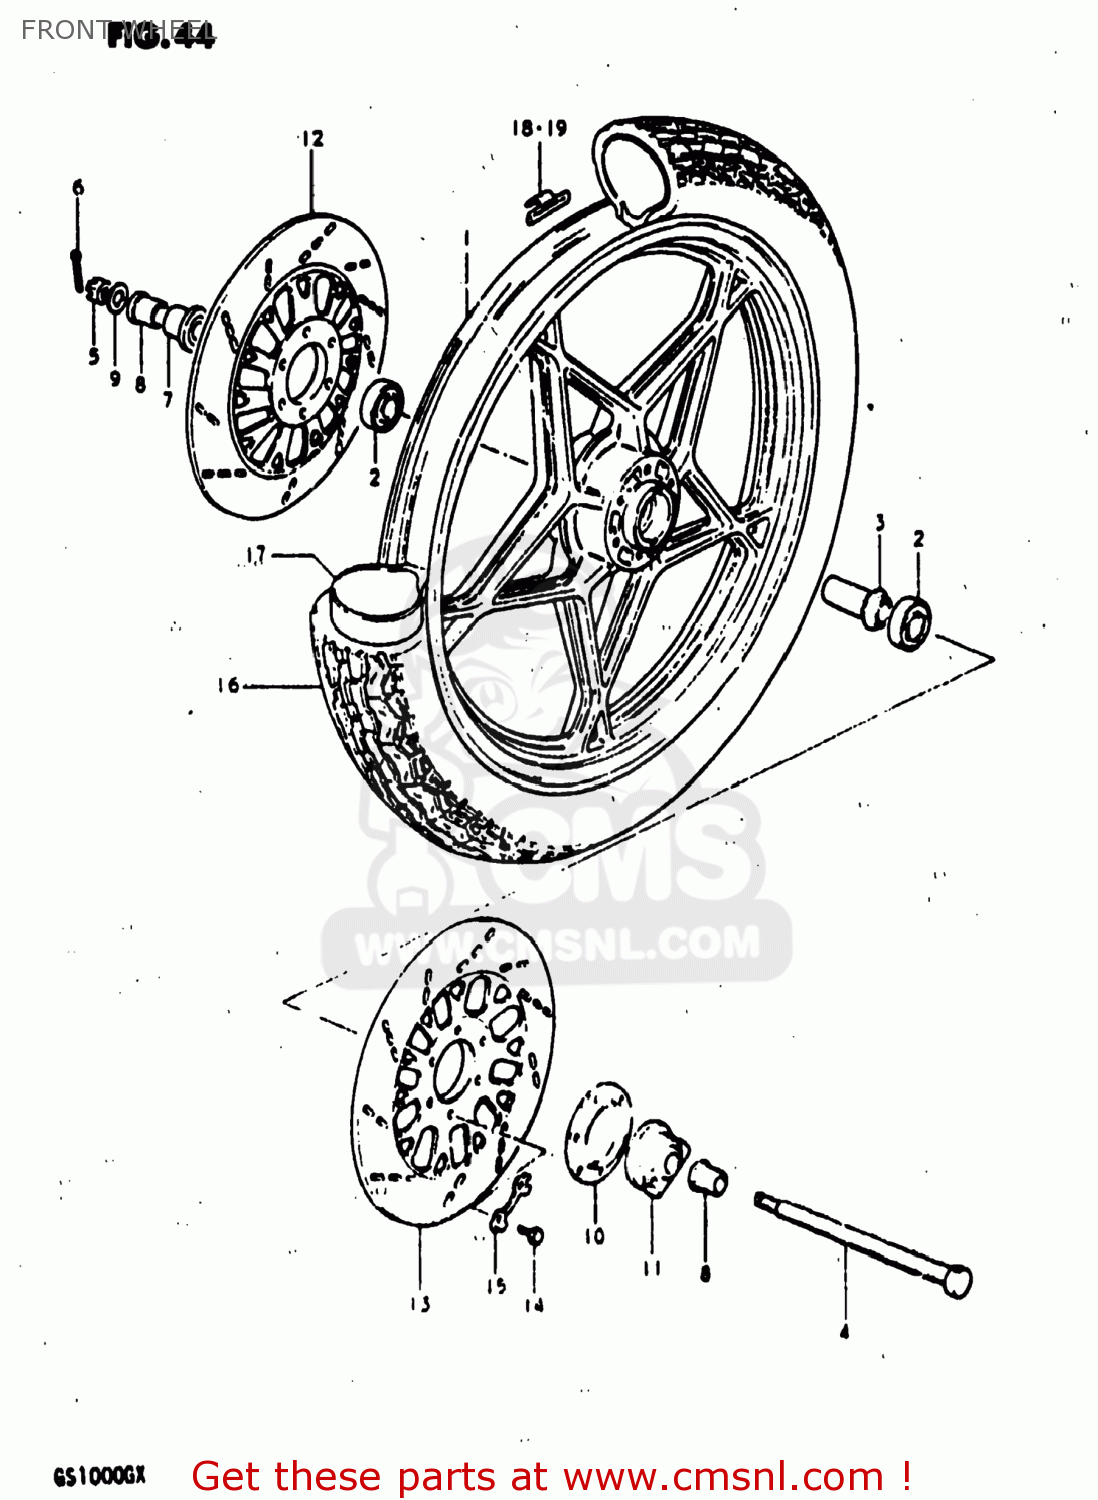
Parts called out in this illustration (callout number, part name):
1	CASTING WHEEL,FRONT
2	BEARING
3	SPACER,FR HUB BEARING
4	AXLE,FR
5	NUT 12MM
6	COTTER PIN
7	SPACER,FR AXLE,R
8	SPACER,FR AXLE,L
9	WASHER
10	DUST SEAL,SPEEDOMETER GEAR BOX
11	BOX ASSEMBLY,SPEEDOMETER GEAR
12	DISC,FR BRAKE,R
13	DISC,FR BRAKE,L
14	BOLT(8X25)
15	WASHER
16	TIRE,FRONT
17	TUBE,INNER
18	BALANCER,WHEEL
19	BALANCER,WHEEL
